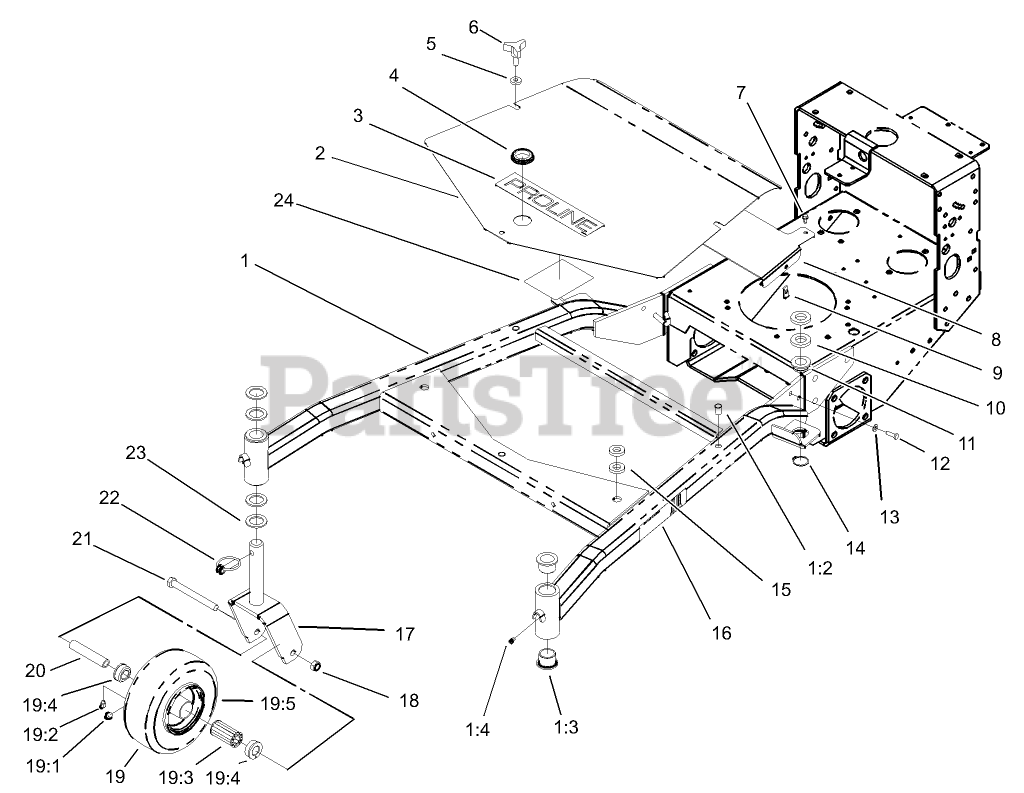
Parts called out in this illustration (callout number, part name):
1	CARRIER FRAME ASM
1:2	INSERT-NUT
1:3	BUSHING
1:4	FITTING-GREASE
2	COVER-FRAME, CARRIER
4	GROMMET-RUBBER
5	WASHER-RUBBER
7	SCREW
8	SHIELD-HEAT
9	NUT-SPEED
10	SPACER-SUPPORT, DECK
11	BUSHING-DECK
12	SCREW-HH
13	WASHER-FLAT
14	RING-RETAINING
15	SPACER
16	DECAL-HOC
17	FORK-CASTOR
18	NUT-HEX
19	CASTER WHEEL ASM
19:1	STEM-VALVE
19:2	FITTING-LUBE, 45 DEG
19:3	BEARING
19:4	BEARING-OUTSIDE
19:5	TIRE-TUBELESS
20	BUSHING-SPANNER
21	SCREW-HH
22	PIN-LYNCH
23	WASHER-THRUST
24	DECAL-SERVICE, HYDRO (TBAR)
24	DECAL-SERVICE, GEAR (TBAR)
24	DECAL-SERVICE, GEAR (PISTOL GRIP)
24	DECAL-SERVICE, HYDRO (PISTOL GRIP)
